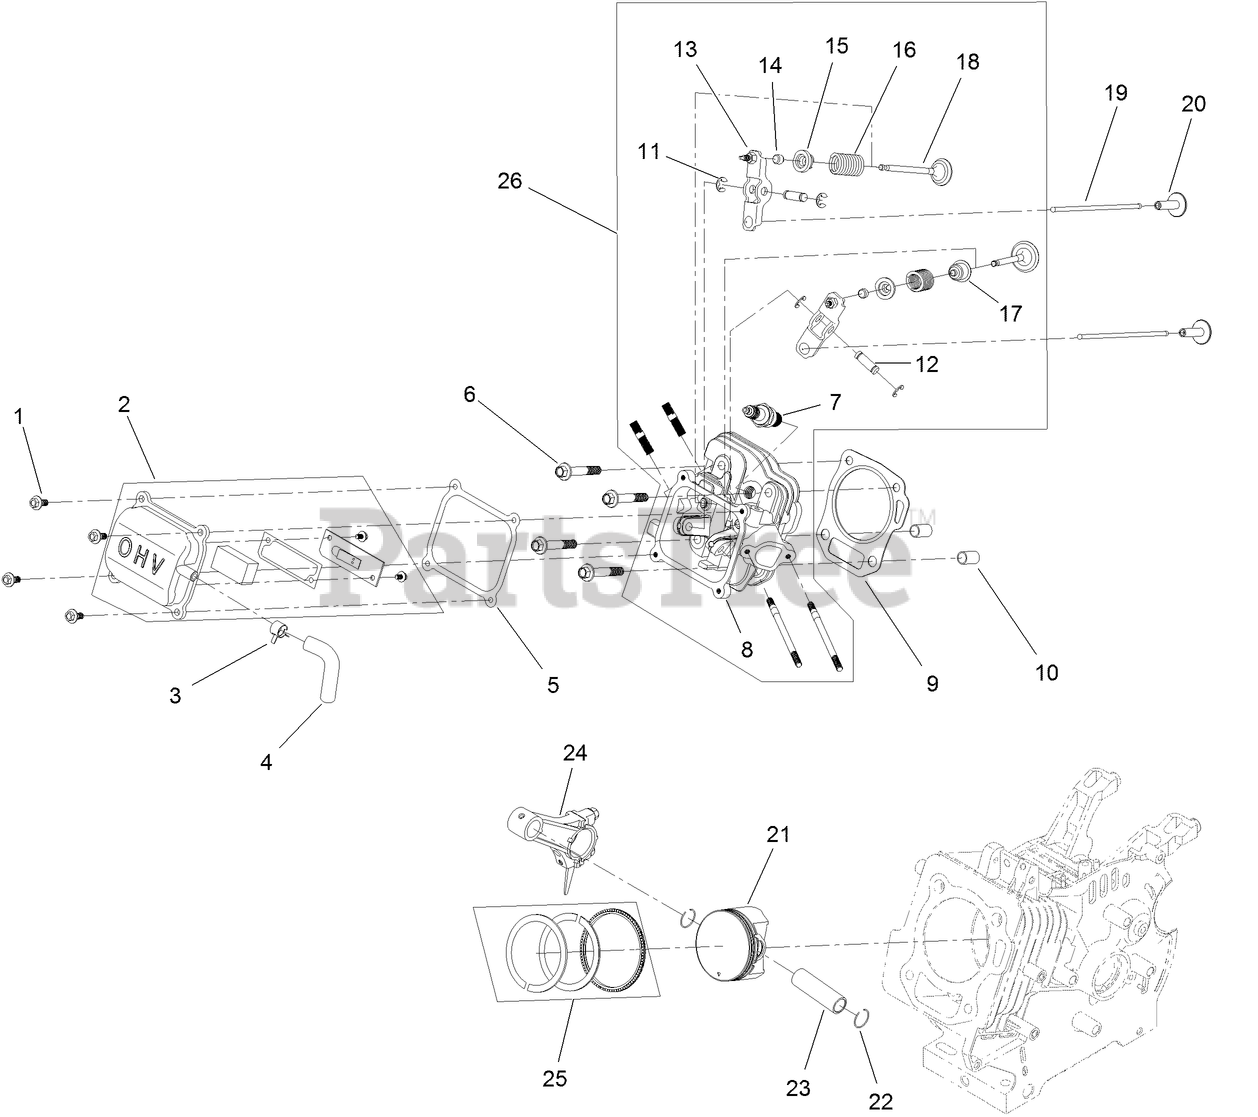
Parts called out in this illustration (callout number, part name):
1	SCREW-HHF
2	VALVE COVER ASM
3	CLAMP-HOSE
4	TUBE-BREATHER
5	GASKET-COVER, VALVE
6	SCREW-FLANGE
7	SPARK PLUG
8	HEAD-CYLINDER
9	GASKET-HEAD
10	PIN-DOWEL
11	E-CLIP
12	PIN-ARM, ROCKER
13	ROCKER ARM ASM
14	ROTATOR-VALVE
15	RETAINER-SPRING, VALVE
16	SPRING-VALVE
17	SEAL-STEM, VALVE
18	SET-VALVE
19	ROD-PUSH
20	TAPPET-VALVE
21	PISTON
22	CLIP-PIN, PISTON
23	PIN-PISTON
24	CONNECTING ROD ASM
25	SET-RING, PISTON
26	COMPLETE HEAD ASM
